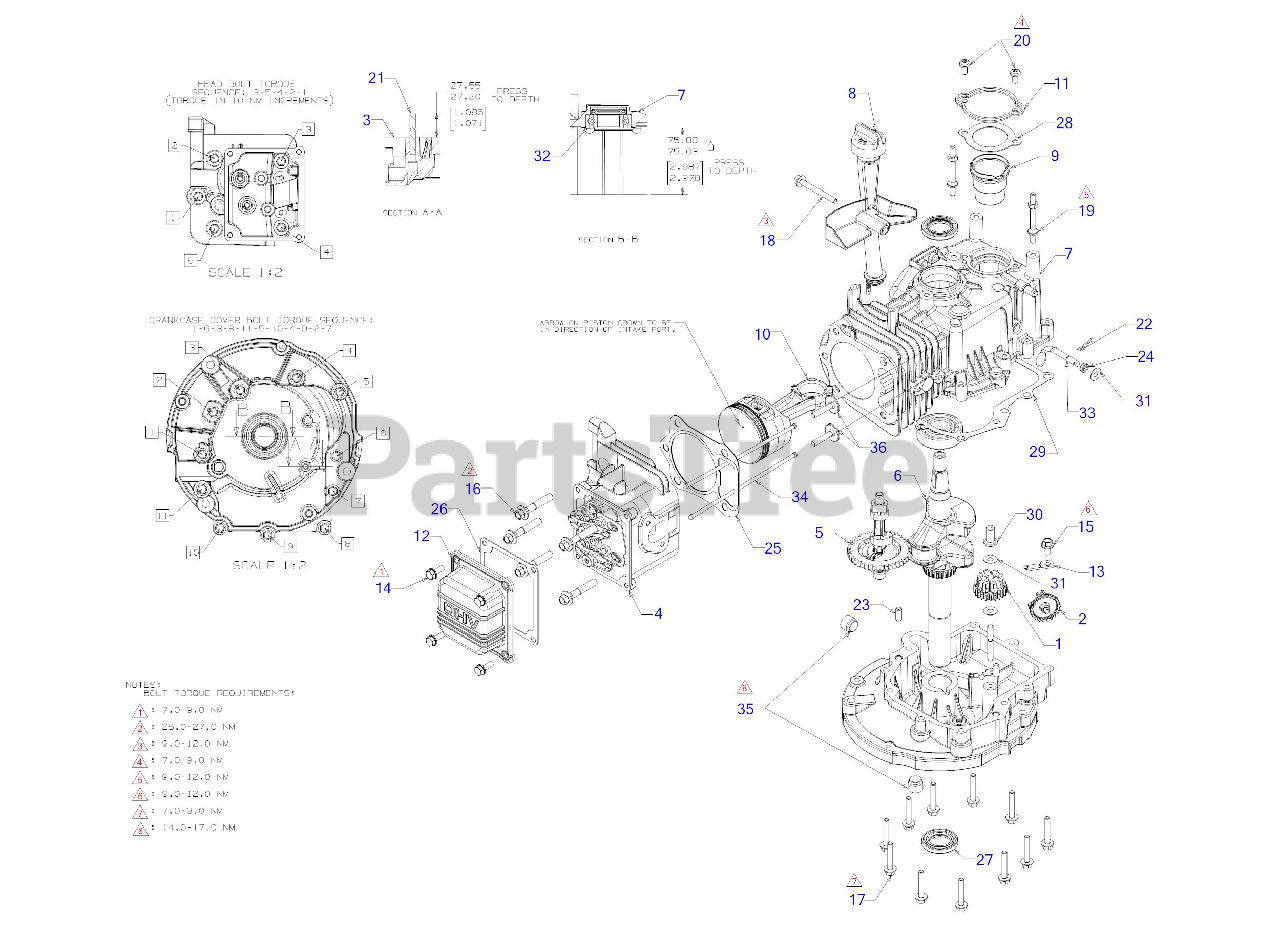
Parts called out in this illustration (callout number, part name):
1	GEAR ASSEMBLY
2	OIL SLINGER GEAR ASSEMBLY
3	CRANKCASE COVER
4	COMPLETE HEAD ASSEMBLY
5	CAMSHAFT ASSEMBLY
6	CRANKSHAFT END
7	CRANKCASE ASSEMBLY
8	ENINE DIPSTICK ASSEMBLY
9	BREATHER BODY ASSEMBLY
10	PISTON ASSEMBLY
11	BREATHER COVER
12	VALVE COVER
13	SUPPORT BRACKET
14	BOLT M6-1 x 16 GR8.8
16	SCREW M8-1.25 x 45:CL5.8
17	HHFLG M6-1 x 35 CL8.8
18	SCREW M6-1:50:CL5.
19	STUD-M6-1:40 LG
20	SCREW M6-1 x 16
21	GOVERNOR SHAFT
22	COTTER PIN
24	OIL SEAL 11 x 4 x 5.2
25	HEAD GASKET
26	VALVE COVER GASKET
27	OIL SEAL 41.25 x 23.6 x 6
28	BREATHER GASKET
31	FLAT WASHER 6.8 x 16 x .4
32	PTO SHAFT BALL BEARING
33	GOVONOR CONTROL ROD
34	PUSH ROD TUBE 195
35	ENGINE PLUG 3/8
36	CAM TPT 195
